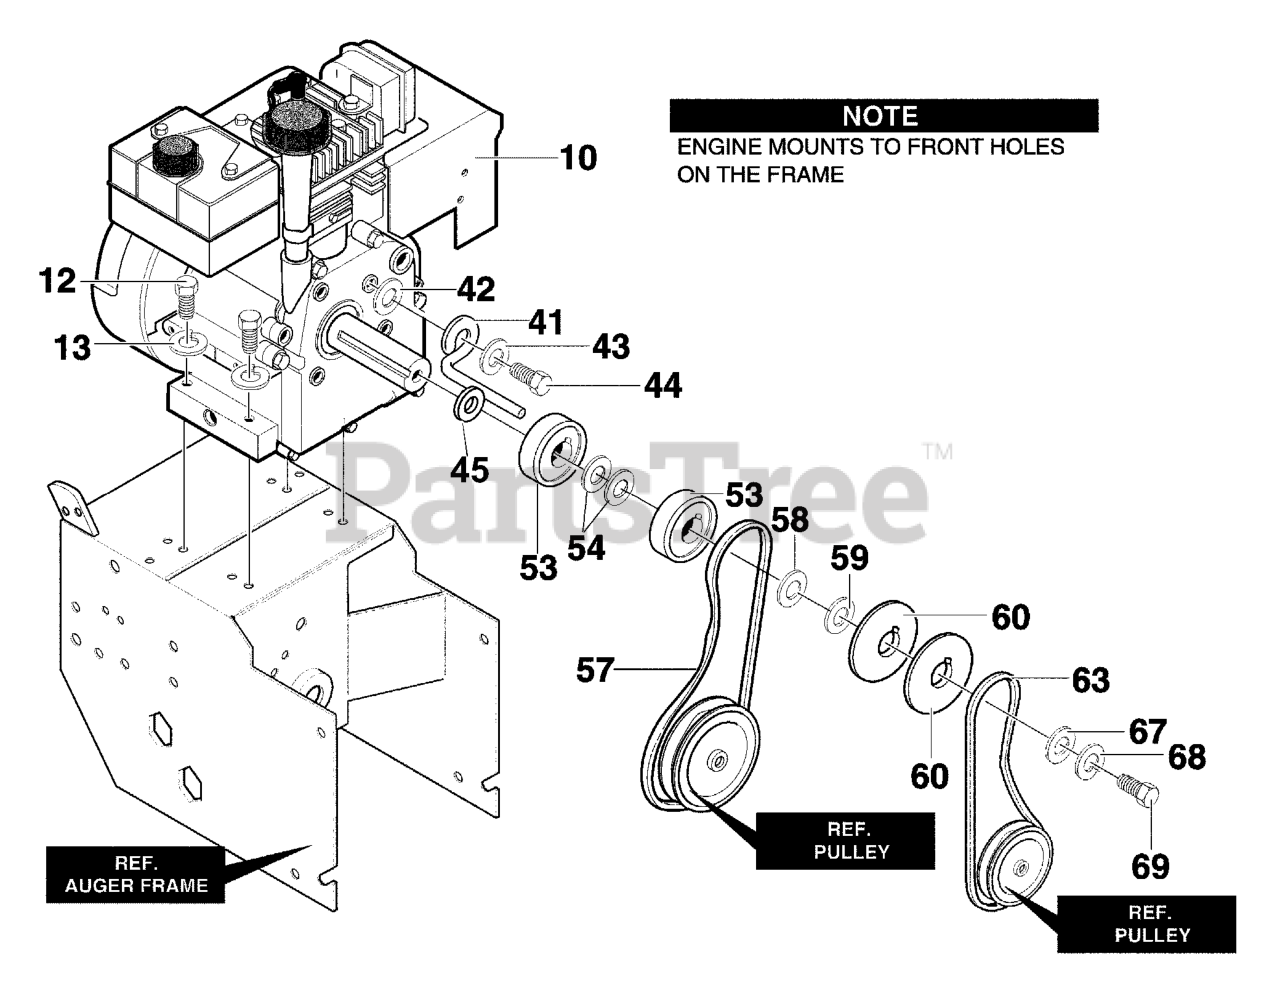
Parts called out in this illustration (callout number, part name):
10	ENGINE
12	SCREW, 5/16-18
13	WASHER
41	GUIDE, ROD BELT
42	PLASTIC WASHER
43	WASHER
44	SCREW, 5/16-24 x 1.00
53	PULLEY, HALF
54	WASHER, FLAT
57	BELT, V 3L 33.13LG
58	FLATWASHER
59	SPACER, SLEEVE
60	PULLEY, ENGINE
67	WASHER, FLAT
69	SCREW, 3/8-24 x 1.00
